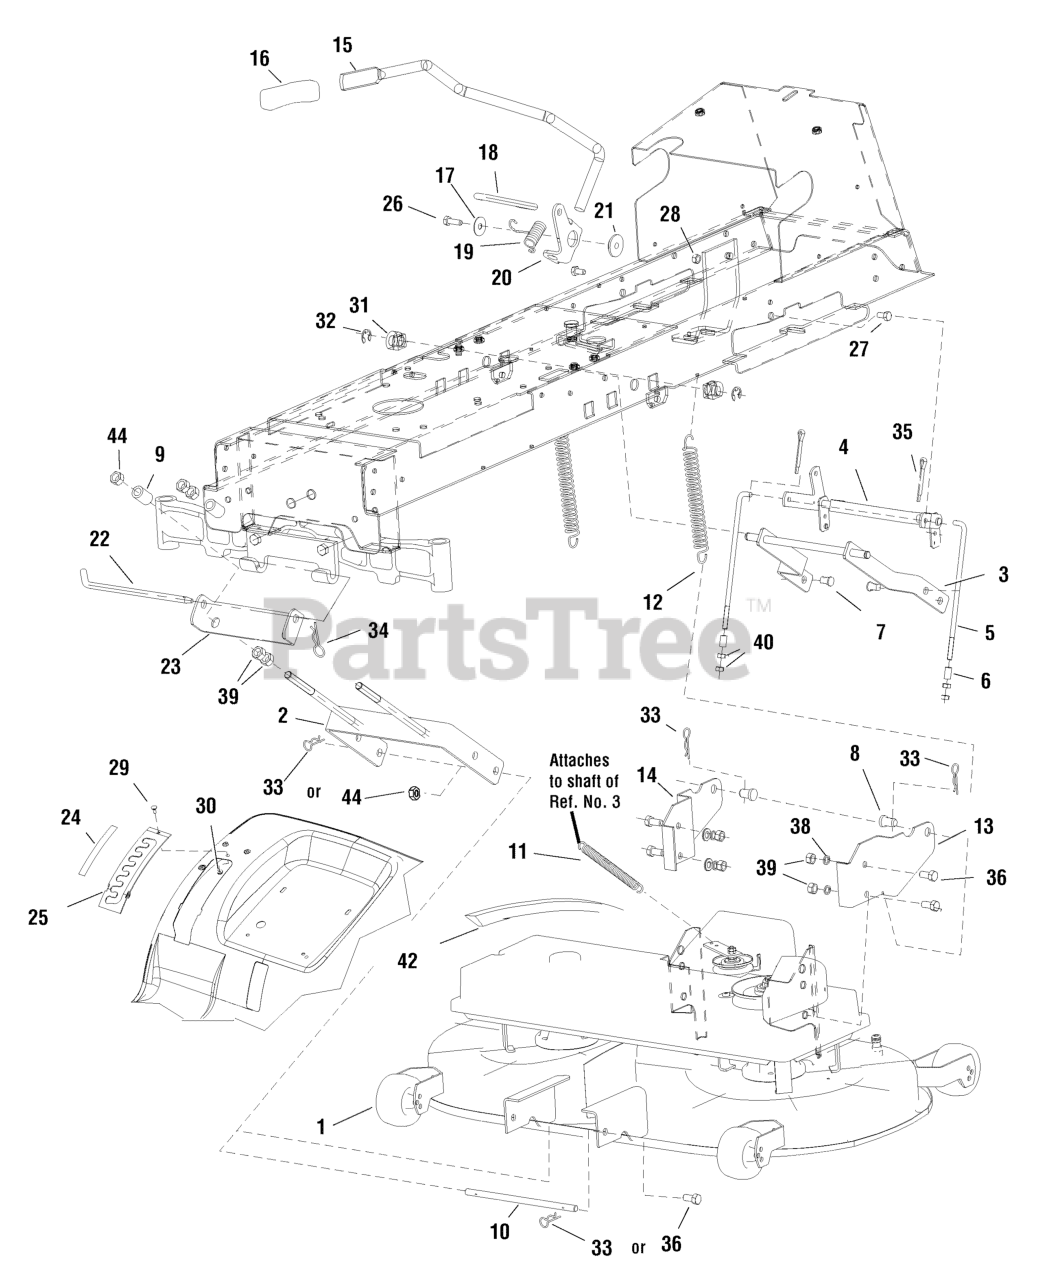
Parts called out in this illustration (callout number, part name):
1	MOWING MECHANISM
2	HINGE, Front
3	ARM, Lift
4	ROD, Lift
5	TIE ROD, Lift
6	DISTANCE, Lift
7	PIN, 0-9016-463
8	PIN, Mowing 1-9310-417
9	DISTANCE, Lift Hitch 0-9521-290
10	STUD
11	SPRING, 0-9746-460
12	SPRING, 0-9746-483
13	HANDLE, Extend, Left
14	HANDLE, Extend, Right
15	ROD, Lift -Change
16	GRIP, Black
17	WASHER, 0.312
18	ROD, Lift .375 dia
19	SPRING, Torsion
20	CLEVIS, Lift
21	SPACER, Pivot
22	PIN, Hitch
23	HANGER, Front
24	DECAL, Height of Cut
25	QUADRANT, Lift Height
26	CAPSCREW, Hex Head, 5/16-18 x 1
27	CAPSCREW, Taptite, 5/16-18 x 5/8
28	NUT, Hex Flange, 5/16-18
29	BOLT, Carriage, 1/4-20 x 5/8
30	NUT, Hex Flange, Whiz 1/4-20
31	BUSHING, 0-9462-202
32	LOCKRING, 12
33	PIN, Flexible 0-9245-240
34	CLIP, Pin Safety
35	SPINDLE, 3.2 x 25
36	BOLT, M12 x 30
38	WASHER, 12
39	NUT, M12
39	NUT, Flange Lock, M12
40	NUT, M10
42	V-Belt, Li, 17 x 1200
44	NUT, M12
